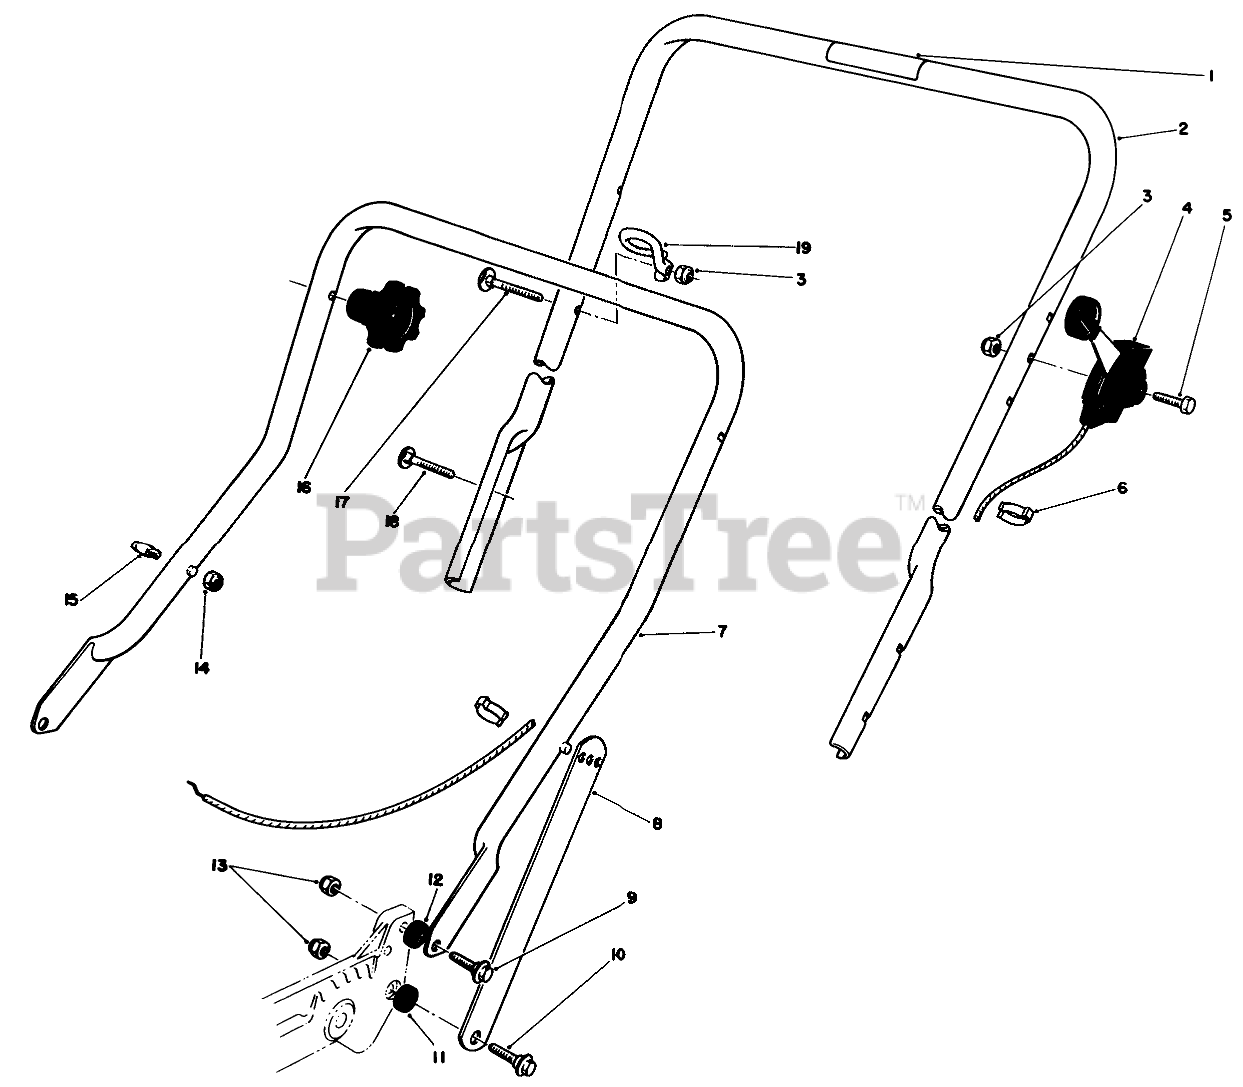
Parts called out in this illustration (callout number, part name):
1	Decal-Danger
2	Handle-Upper (Incl. Ref. #1)
3	NUT-LOCK, NI
4	SERVICE THROTTLE CONTRO
5	SCREW-HH
6	BOWDEN CLIP
7	Handle-Lower
8	Handle Latch
9	SCREW-SHOULDER
10	SCREW-SHOULDER
11	SPACER
12	SPACER
13	NUT-LOCK, NI
14	NUT-LOCK, NI
15	HANDLE PIN
17	HANDLE SCREW
18	5/16-18 X 2 HNDLE SCREW
19	Guide
